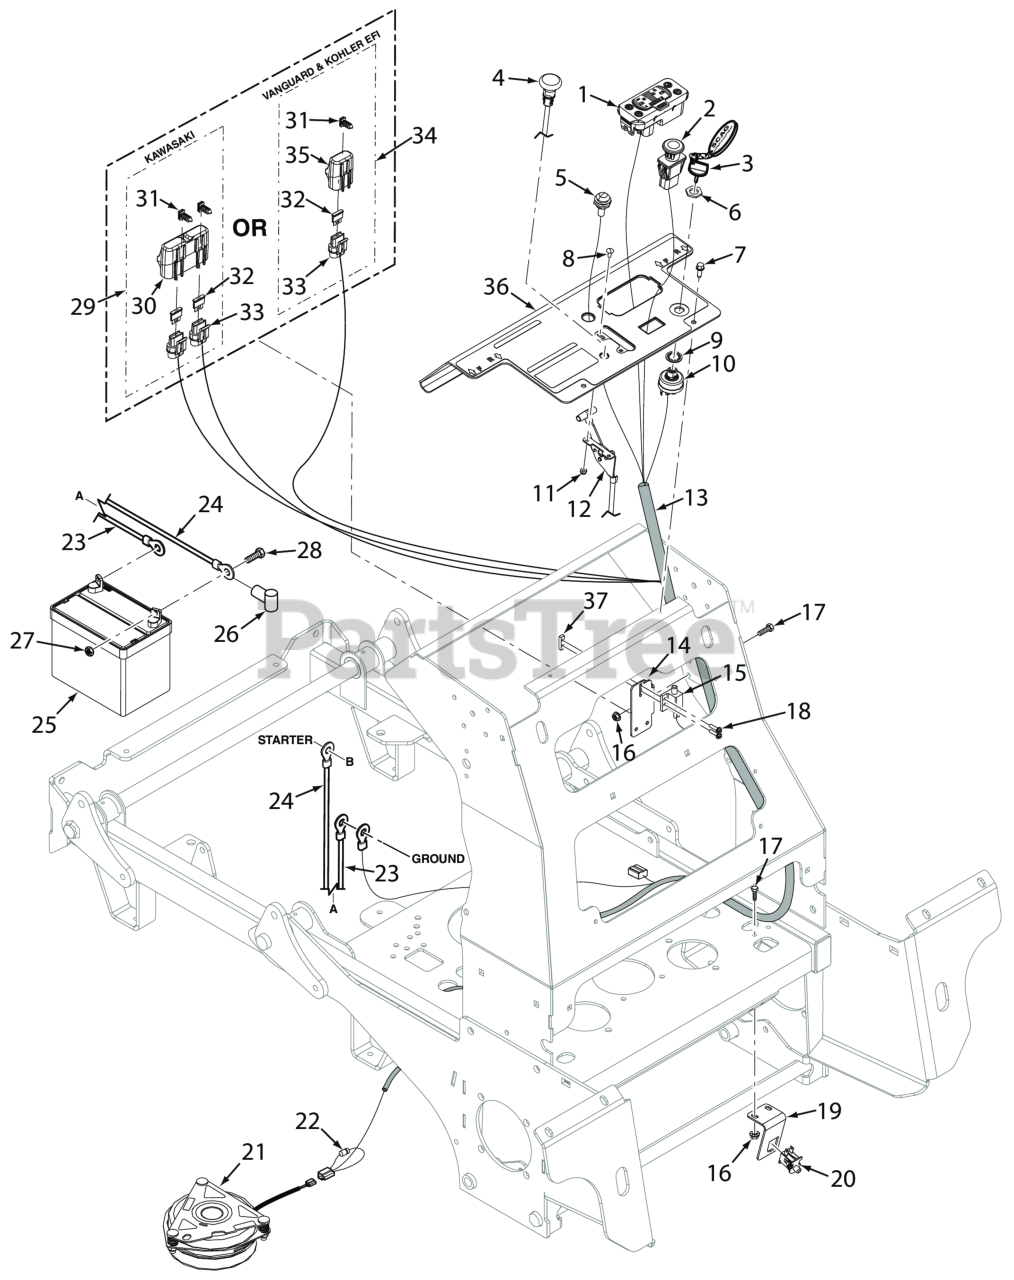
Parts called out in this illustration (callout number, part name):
1	Tiger Eye, Cluster Gauge
2	Switch, PTO - 10 Amp
3	Key, Assembly w/Fob
4	Choke Control (excludes EFI models)
5	Indicator Light, Glow Plugs (Includes Mounting Hardware)
6	Nut, 5/8-32 Special
7	Screw, Self-Tapping 1/4-20 x 3/4
8	Bolt, Carriage #10-24 x 1/2"
9	LOCK WASHER, 5/8" INTERNAL TOOTH
10	KEY SWITCH(INCLUDES MOUNTING HARDWARE)
11	Nut, Elastic Stop #10-24
12	Throttle Control, SVR
13	Wire Harness, SVRII-EFI
14	Bracket, Neutral Switch
15	Switch, Interlock, Park Brake Normally Open
16	NUT, 1/4-20 SERRATED FLANGE HEX HEAD
17	BOLT, HEX HEAD, 1/4-20 X 3/4 GR.5
18	Screw, Hex-Slotted Washer Head #10 32 x 3/4"
19	Switch Bracket, Operator Presence
20	SWITCH, NEUTRAL INTERLOCK
21	Clutch w/Tag GT3.5--FE05 (61)
22	Diode, 600V 6 Amp
23	Battery Cable, 39" Black (26EFI) - Kohler
24	Battery Cable, 44" Red w/Braid (26EFI) - Kohler
25	Battery, 350 CCA (not available through Scag)
26	RUBBER BOOT
27	Nut, 1/4 - 20 Hex
28	BOLT, HEX HEAD, 1/4-20 X 3/4 GR.5
29	Double Fuse Assy.
30	Cover, Sealed Double
31	Clip, Fuse Holder
32	FUSE, 20 AMP BLADE TYPE AUTOMOTIVE
33	Fuse Holder Assembly
34	Single Fuse Assy., Excluding Fuse
35	Cover, Sealed Single
36	Control Panel w/Decal
37	Plate, Threaded
